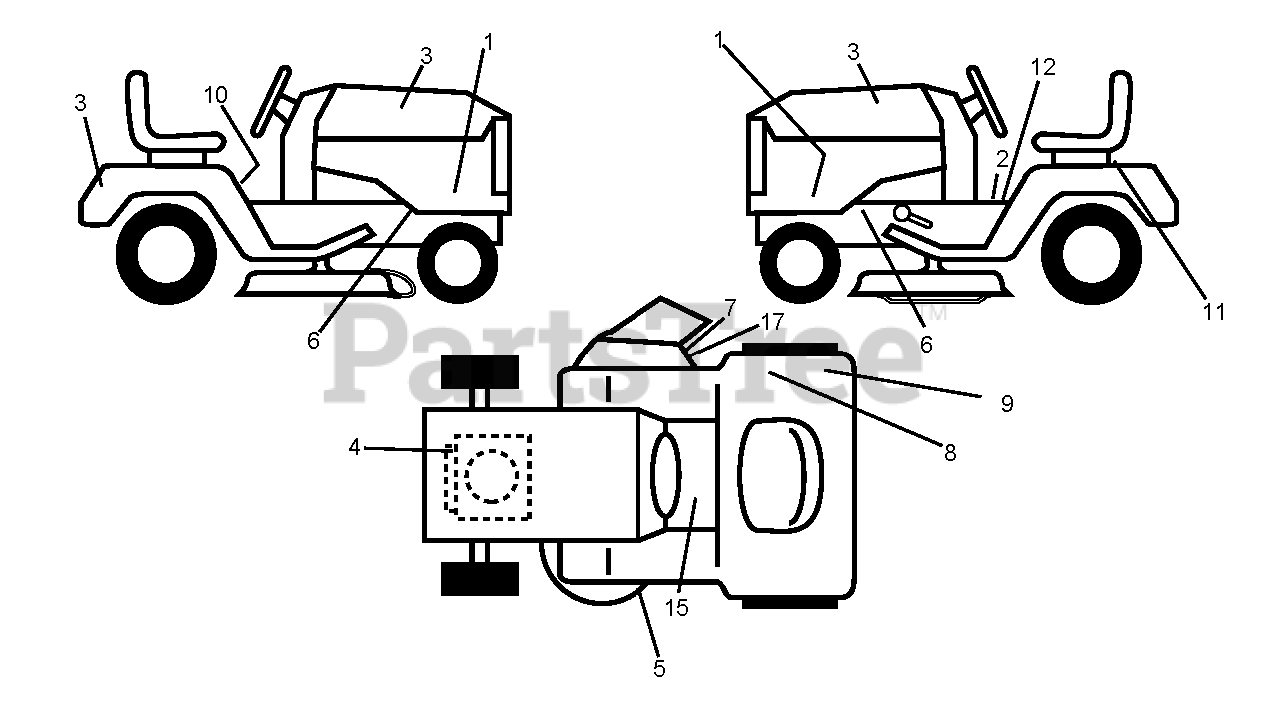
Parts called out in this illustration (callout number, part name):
2	DECAL PARK BRAKE
3	RP.DECAL.BADGE.170MM.TEXTLOGO
4	DECAL
5	DECAL V BELT SCHEMATIC
7	DECAL.INTERNATIONL.CUTFINGER
8	DECAL 80 DBA
9	DECAL
10	LABEL
11	DECAL BTRY SYMBOLS
12	DECAL
15	DECAL
17	DECAL, DEFLECT WARNING
